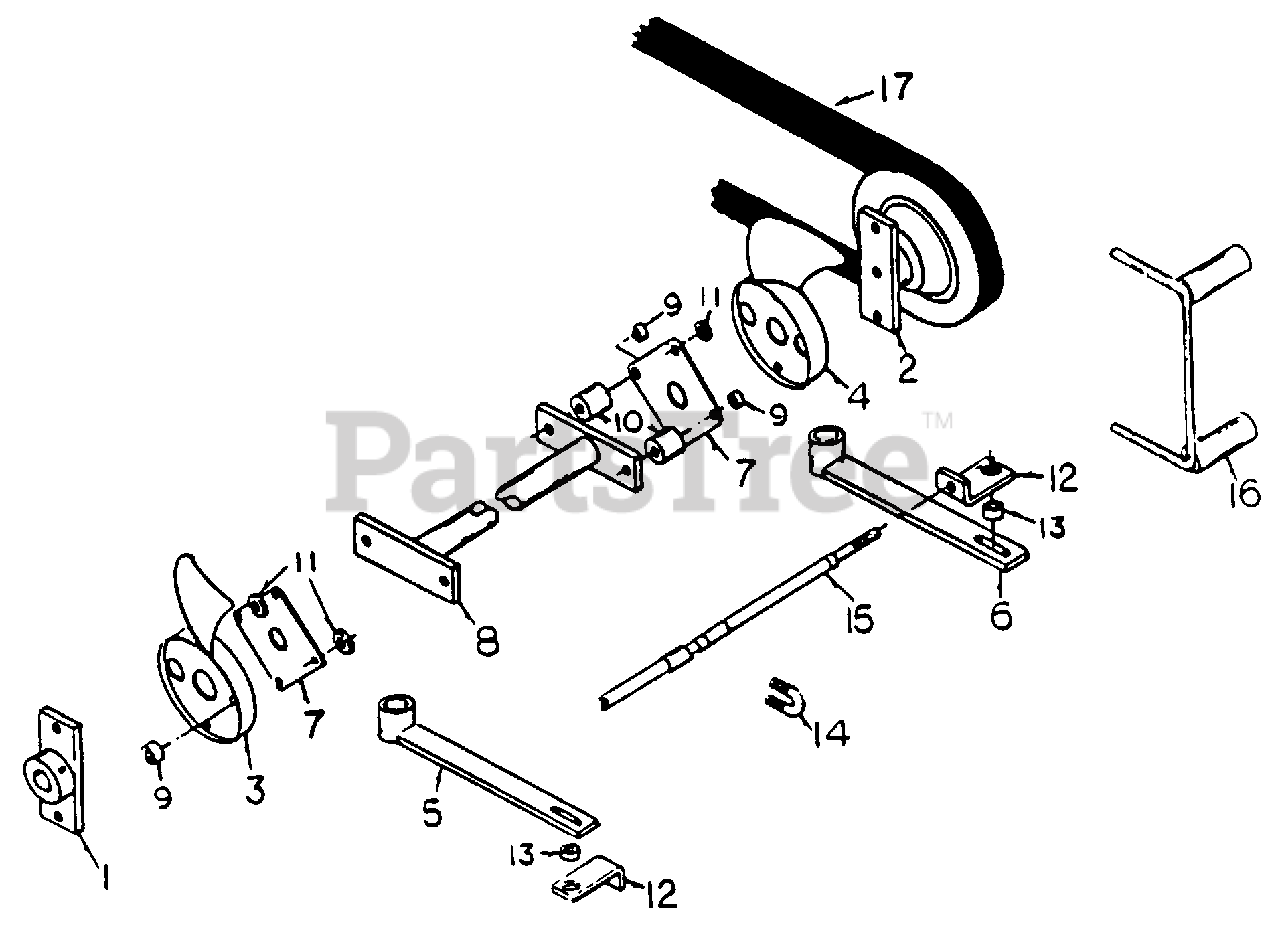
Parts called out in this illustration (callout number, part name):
1	Hub w/Drive Plate
2	Pulley w/Drive Plate
5	Transmission Arm, LH
6	Transmission Arm, RH
7	Drlve Plate
8	Transmlsslon Cross Shaft
11	Washer, 1/4", 10 Ga.
12	Steering Cable End
13	Bushlng, Steerlng lever
14	Steerlng Cable Clamp
15	Steerlng Cable
16	Belt Retainer, Transmisslon
